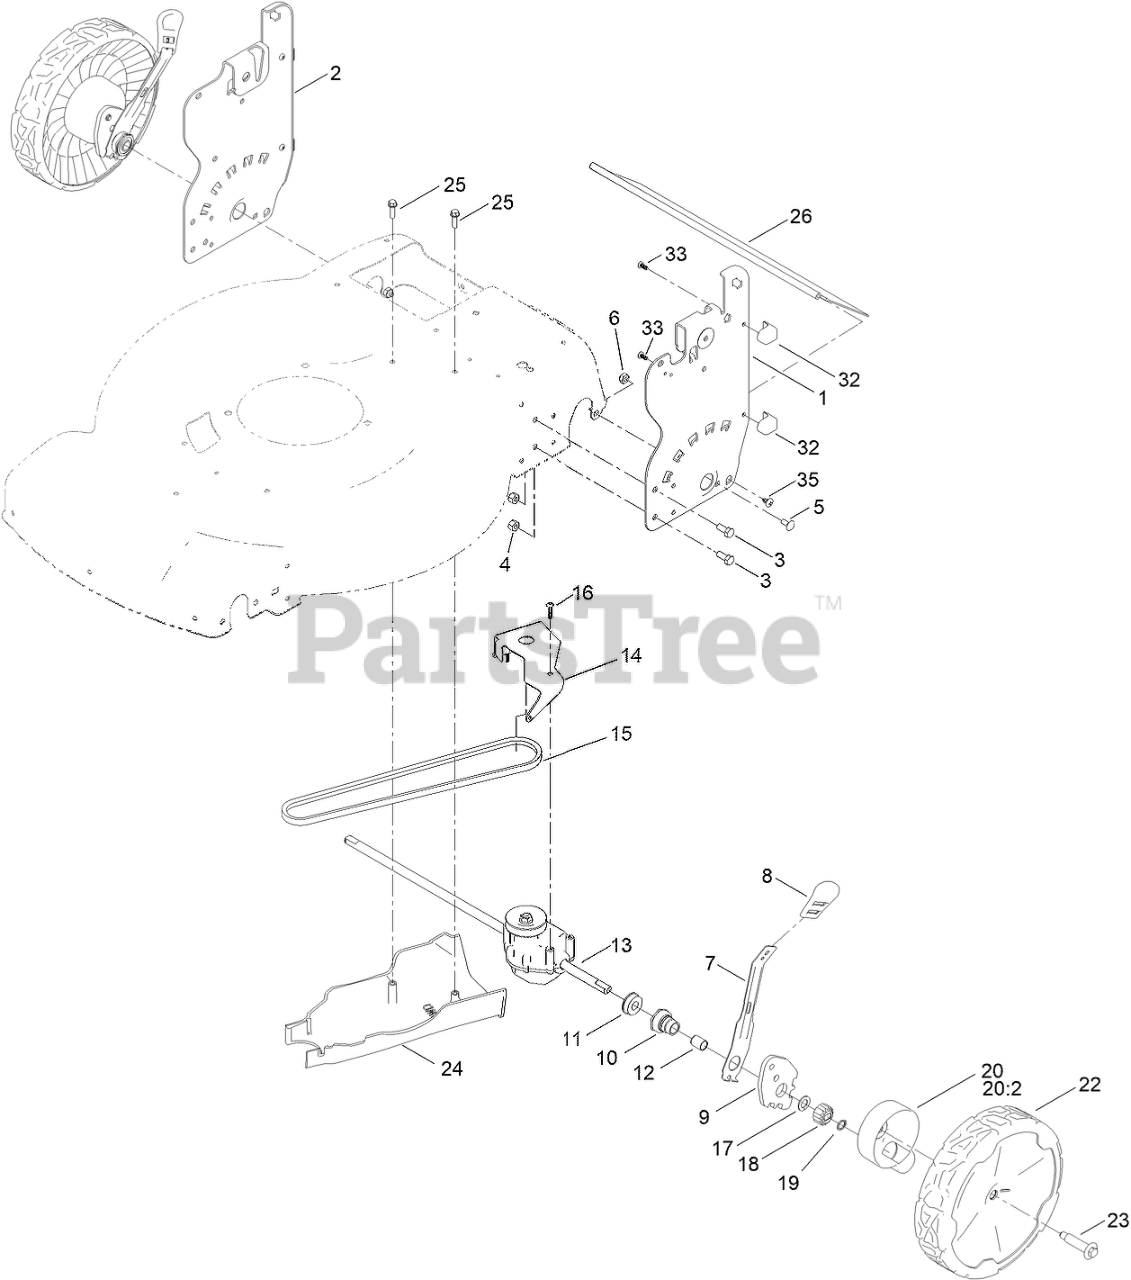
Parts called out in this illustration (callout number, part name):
1	PLATE-HOC, LH
2	PLATE-HOC, RH (2 HOLE)
3	SCREW-HH
4	NUT-HEX
5	BOLT-CARR
6	NUT-LOCK
7	ARM-SPRING
8	KNOB-HOC
9	ARM-PIVOT, REAR
10	RETAINER-BUSHING, HOC
11	BEARING-BALL
12	BUSHING-SLEEVE
13	TRANSMISSION-RWD
14	BRACKET-TRANSMISSION
15	V-BELT
16	SCREW-PLASTITE
17	WASHER-THRUST
18	GEAR-PINION, 15T
19	RING-RETAINING
20	ASM-COVER, GEAR (DK GRAY)
20:2	WASHER-STEPPED
22	ASM-9.65" WHEEL, GEARED
23	WHEEL BOLT
24	COVER-BELT, RWD
25	SCREW-PLASTITE, HWH
26	SHIELD-TRAILING
32	PAD-SMART STOW
33	SCREW-PPH
35	SCREW-THD
